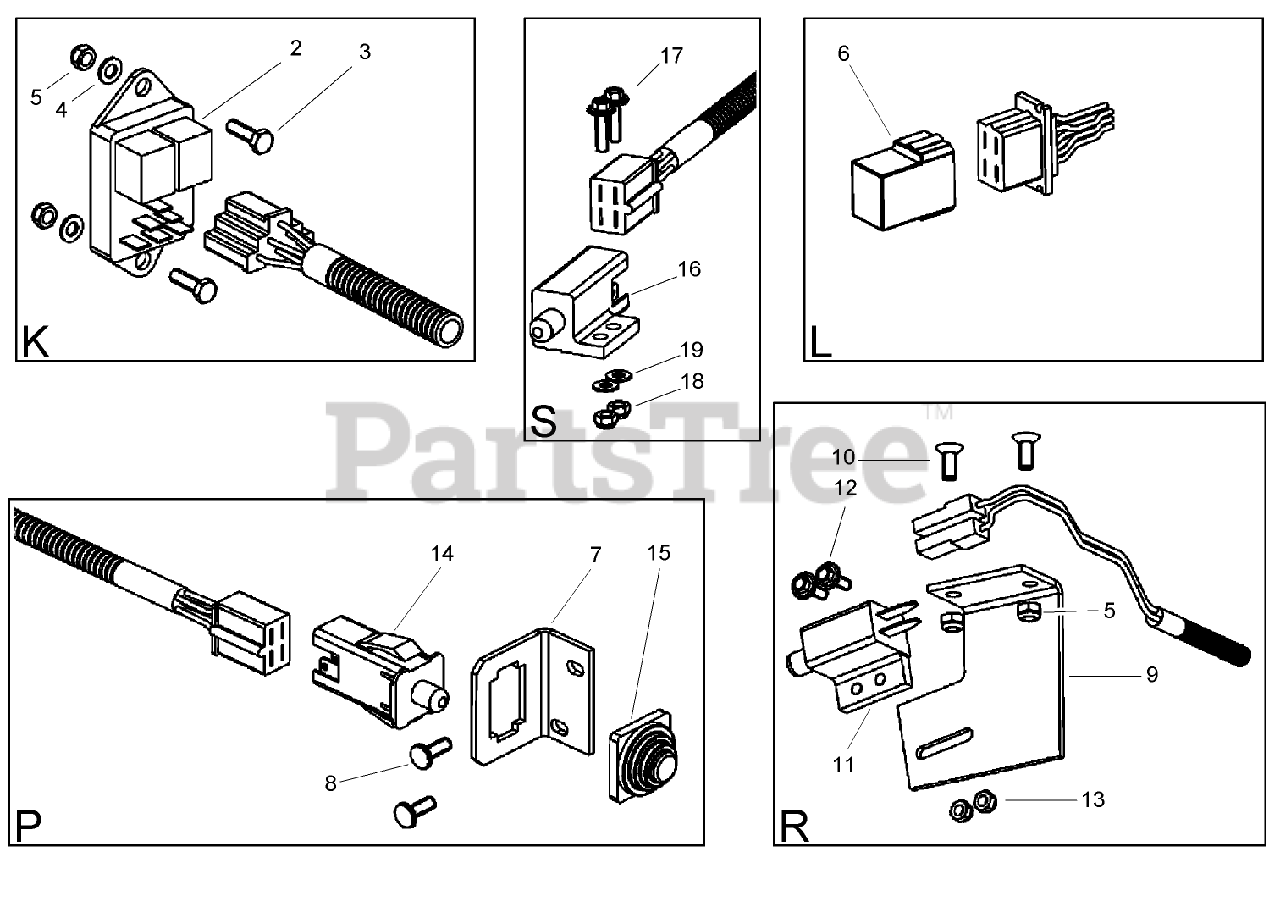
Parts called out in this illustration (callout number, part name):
2	MODULE-CLUTCH
3	SCREW-HH
4	WASHER
5	NUT-LOCK
6	CIRCUIT-MEMORY
7	Holder-Switch
9	HOLDER-SWITCH
11	SWITCH-POLE, SINGLE
13	NUT-HEX
14	SWITCH-DELTA
15	Cover-Switch
16	Switch-Delta
18	NUT-LOCK
19	WASHER
